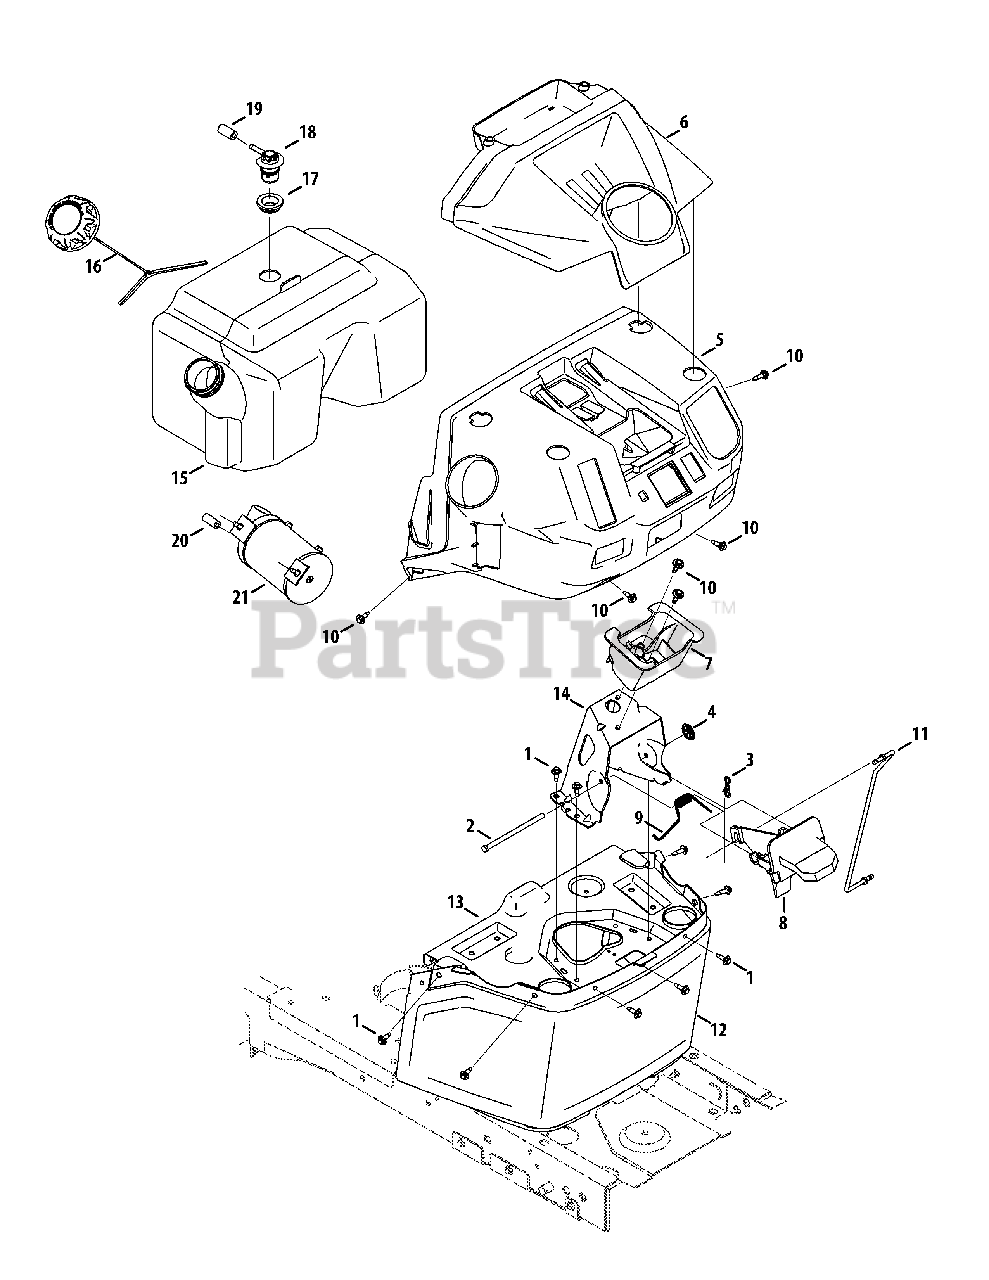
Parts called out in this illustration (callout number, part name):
1	Screw, M6-1 x .625
2	Hinge Pin, .25 Dia x 4.50 LG
3	Pin, Cotter, Bow-Tie 72
4	Push Nut, .25 dia.
5	Upper Dash
6	Dash Cap
7	Steering Shaft Bearing
8	Dash Lever
9	Torsion Spring, .330 ID
10	Shoulder Screw, .368 x .115, M6-1
11	Control Rod
12	Lower Dash
13	Dash Plate
14	Steering Bearing Mounting Bracket
15	Tank, Fuel, 3 Gal.
16	Cap, Fuel Carb
17	Grommet, Rubber, 23.0 ID
18	Valve, Rollover Grommet
20	Hose, Fuel, Low Perm, 7/32 Yellow (CARB)
21	Carbon Canister (CARB)
